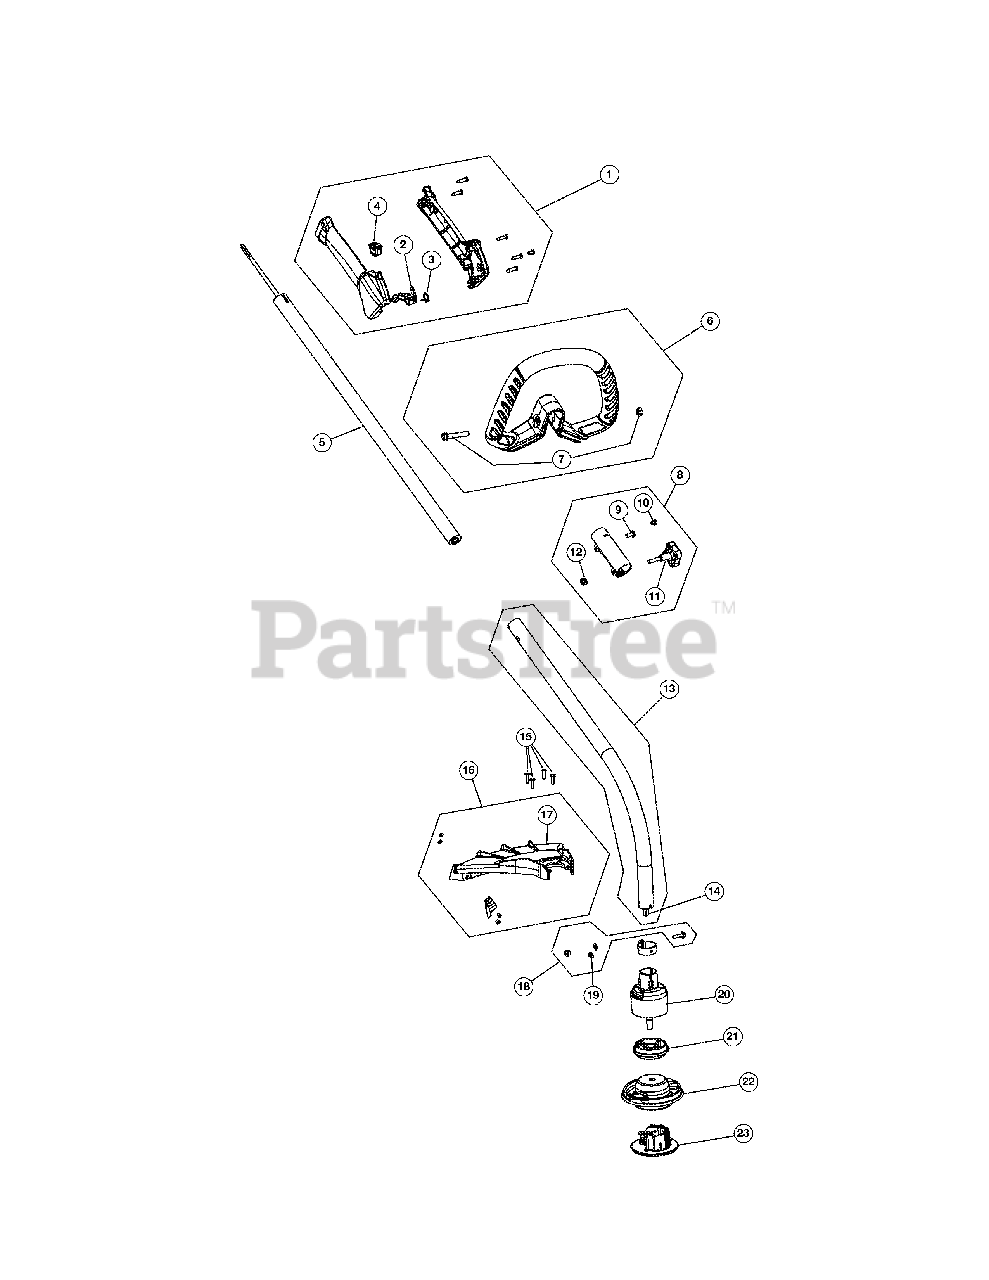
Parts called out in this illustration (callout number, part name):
1	Throttle Housing Assembly (Incl. Ref No. 2-4)
2	Throttle Trigger
3	Throttle Trigger Spring
4	Switch Assembly
5	Upper Drive Shaft Housing
6	Deluxe D-Handle Assembly (Incl. Ref No. 7)
8	Click Link Coupler (Incl. Ref No. 9-12)
11	Adjustment Knob (Incl. Ref No. 12)
13	Lower Drive Shaft Housing (Incl. Ref No. 14)
14	Lower Flexible Drive Shaft
15	Shield Mount Hardware
16	Blade Assembly
17	Shield Assembly (Incl. Ref No. 16)
18	Lower Clamp Assembly (Incl. Ref No. 19)
19	Anti-Rotation Screw
20	Bushing Housing Assembly
21	Adapter
22	Cutting Head Assembly
23	Glide Plate
